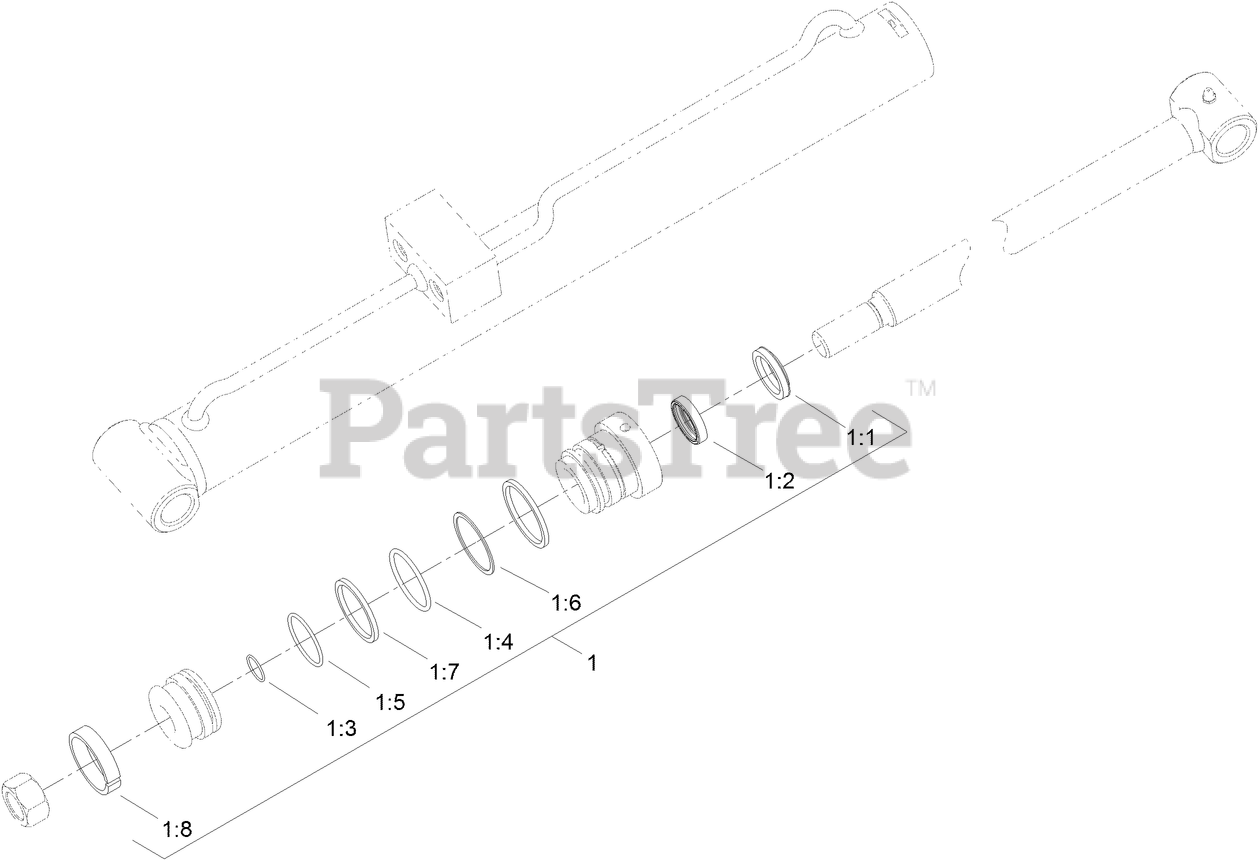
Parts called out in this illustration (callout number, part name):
1	SEAL KIT
1:1	Deck ASM
1:2	SEAL
1:3	Deck ASM
1:4	Deck ASM
1:5	Deck ASM
1:6	Deck ASM
1:7	SEAL
1:8	Deck ASM
